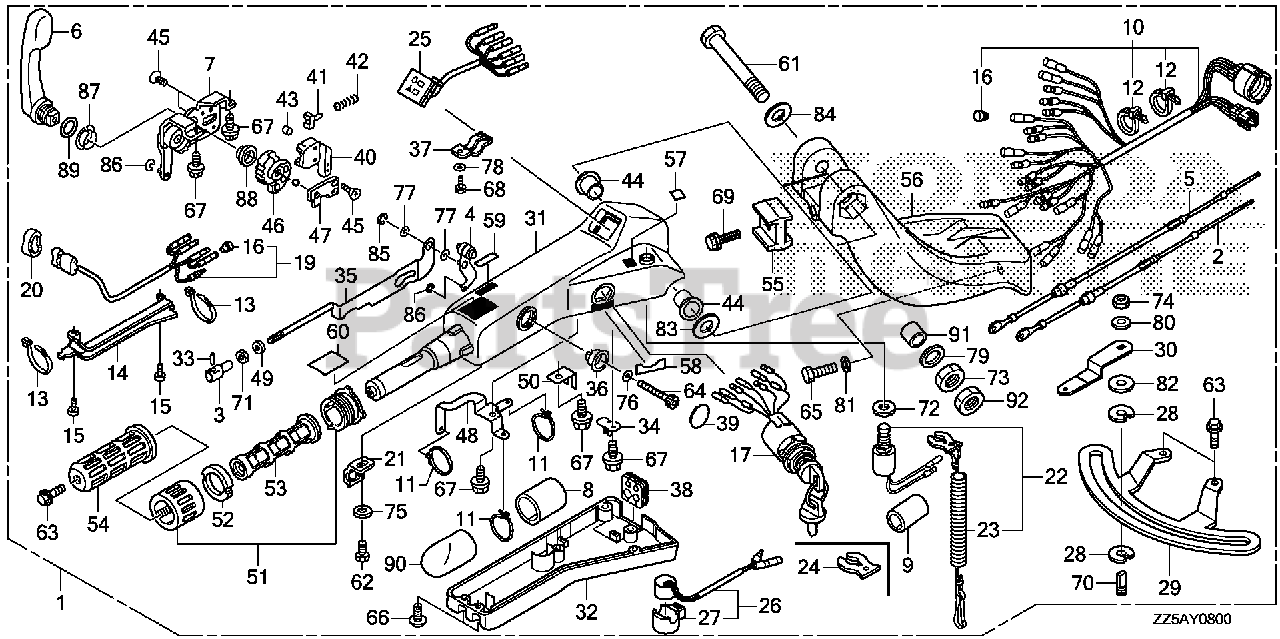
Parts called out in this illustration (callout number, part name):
1	HANDLEBAR KIT *NHB14M* (AQUA MARINE SILVER METALLIC)
2	CABLE, THROTTLE
3	PIVOT, THROTTLE CABLE
4	ARM, THROTTLE
5	CABLE, SHIFT
6	LEVER, SHIFT
7	FRAME ASSY., SHIFT
8	TUBE (38.1X40)
9	TUBE
10	CABLE ASSY., LONG HANDLE (A)
11	BAND (CONVEX CV-150)
12	BAND (CONVEX CV-200)
13	BAND (CONVEX)
14	COVER, WIRE
15	SCREW
16	PLUG, CONNECTOR (INNER)
17	SWITCH ASSY., COMBINATION
19	SWITCH ASSY., POWER TILT
20	GROMMET
21	HOLDER, SWITCH
22	SWITCH ASSY., EMERGENCY STOP
23	WIRE, EMERGENCY
24	CLIP, EMERGENCY LOCK
25	LAMP ASSY., INDICATOR
26	BUZZER ASSY., WARNING
27	SUSPENSION, WARNING BUZZER
28	BLOCK, FRICTION
29	PLATE, FRICTION
30	LEVER, FRICTION
31	HOUSING *NHB14M* (AQUA MARINE SILVER METALLIC)
32	COVER, HANDLEBAR (LOWER)
33	PIN, THROTTLE CABLE
34	BRACKET, CABLE
35	PLATE ASSY., LOCK
36	STOPPER
37	PLATE, GUIDE
38	GROMMET
39	CAP
40	GUIDE, SPRING
41	ACTUATOR
42	SPRING, COIL
43	ROLLER
44	BUSH, HANDLEBAR
45	SCREW (M5X14)
46	GEAR, SHIFT
47	PLATE, BALL GUIDE
48	BRACKET
49	ROD, GROMMET
50	CLAMP, BRACKET
51	GRIP ASSY., THROTTLE FRICTION
52	PAD, THROTTLE FRICTION
53	PIPE, GRIP
54	RUBBER, GRIP
55	BLOCK, HEIGHT ADJUSTER
56	BRACKET, STEERING *NHB14M* (AQUA MARINE SILVER METALLIC)
57	MARK, EMERGENCY SWITCH INDICATION (EU)
58	MARK, STARTER (ENGLISH)
59	MARK, CHANGE
60	MARK, THROTTLE (ENGLISH)
61	BOLT, HEX. (12X80)
62	BOLT (M5X8)
63	BOLT, FLANGE (6X12)
64	BOLT (M8X50)
65	BOLT, HEX. (10X32)
66	BOLT (M5X12)
67	BOLT (M6X12)
68	BOLT (M5X12)
69	BOLT, FLANGE (8X28)
70	BOLT, STUD (8X26)
71	NUT, HEX. (5MM)
72	NUT, HEX. (16MM)
73	NUT, HEX. (12MM)
74	NUT, SELF-LOCK (8MM)
75	WASHER (5MM)
76	WASHER (8MM)
77	WASHER (10MM)
78	WASHER (5MM)
79	WASHER, WAVE (14MM)
80	WASHER (8MM)
81	WASHER (10MM)
82	WASHER, NYLON (8MM)
83	WASHER, PLAIN (12MM)
84	WASHER, PLAIN (12MM)
85	E-RING
86	E-RING
87	BEARING
88	BEARING
89	O-RING (20.6X1.9)
90	TUBE, CORD (40MM)
91	COLLAR, DISTANCE (12.2X23X16)
92	NUT, HEX. (12MM)
